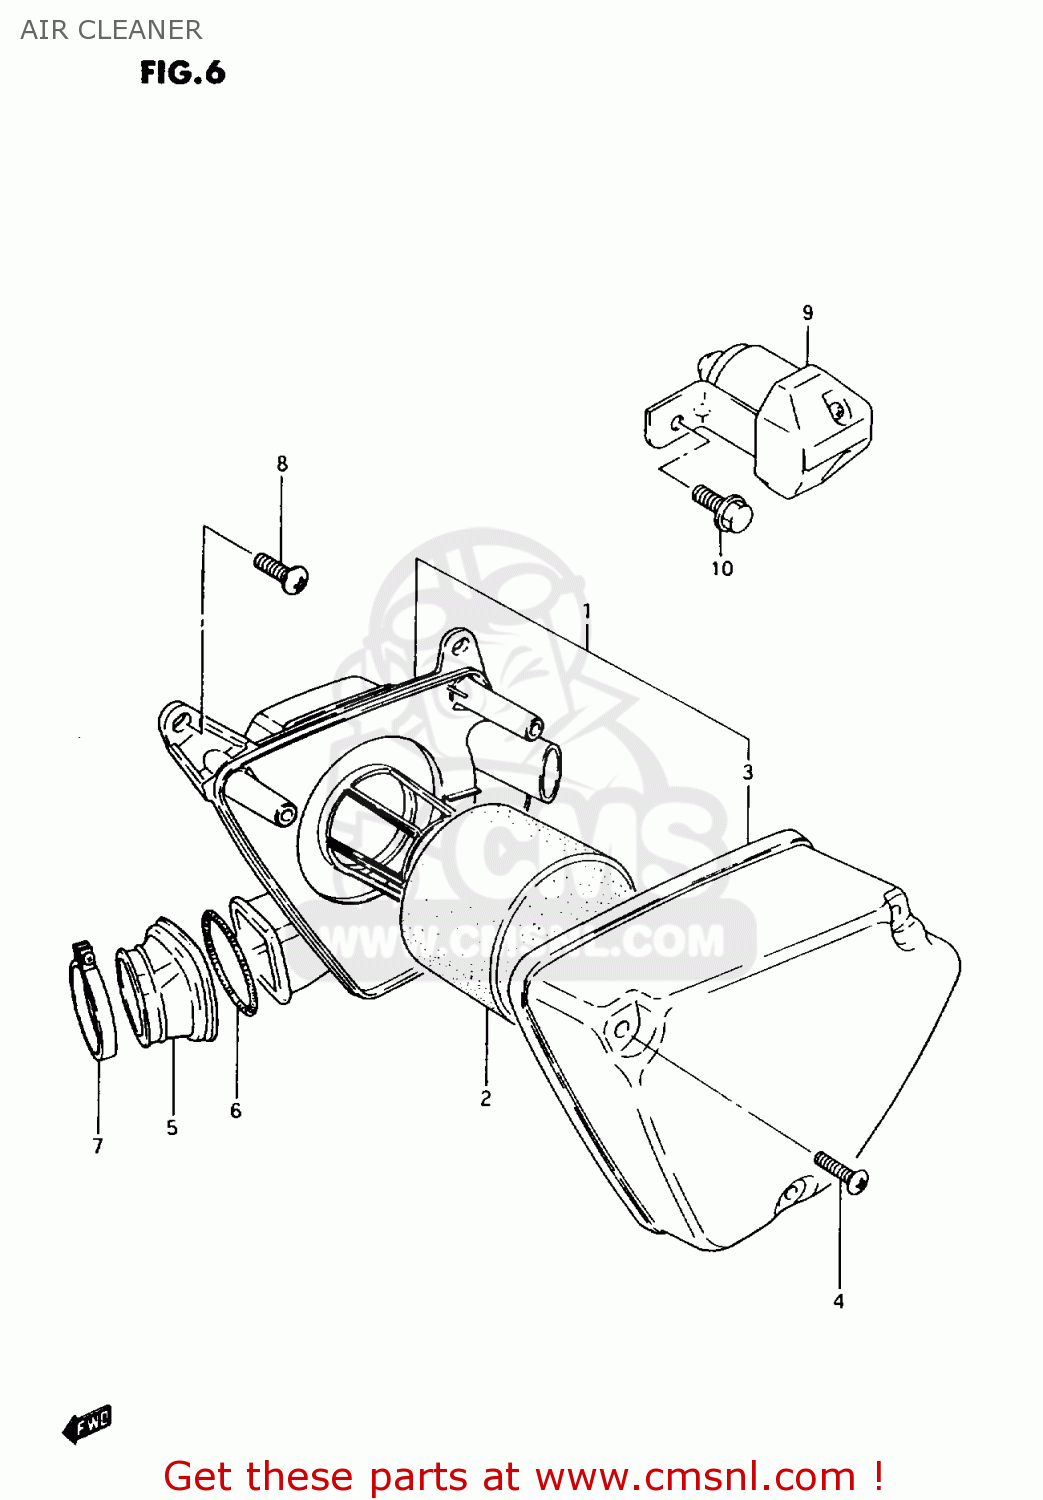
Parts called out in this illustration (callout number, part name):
1	CLEANER ASSY,AIR
2	FILTER,AIR CLEANER
3	CAP
4	SCREW
5	TUBE,OUTLET
6	CLAMP,CLEANER SIDE
7	CLAMP
8	SCREW(6X16)
9	COMPENSATOR ASSY, ALTITUDE
10	BOLT
